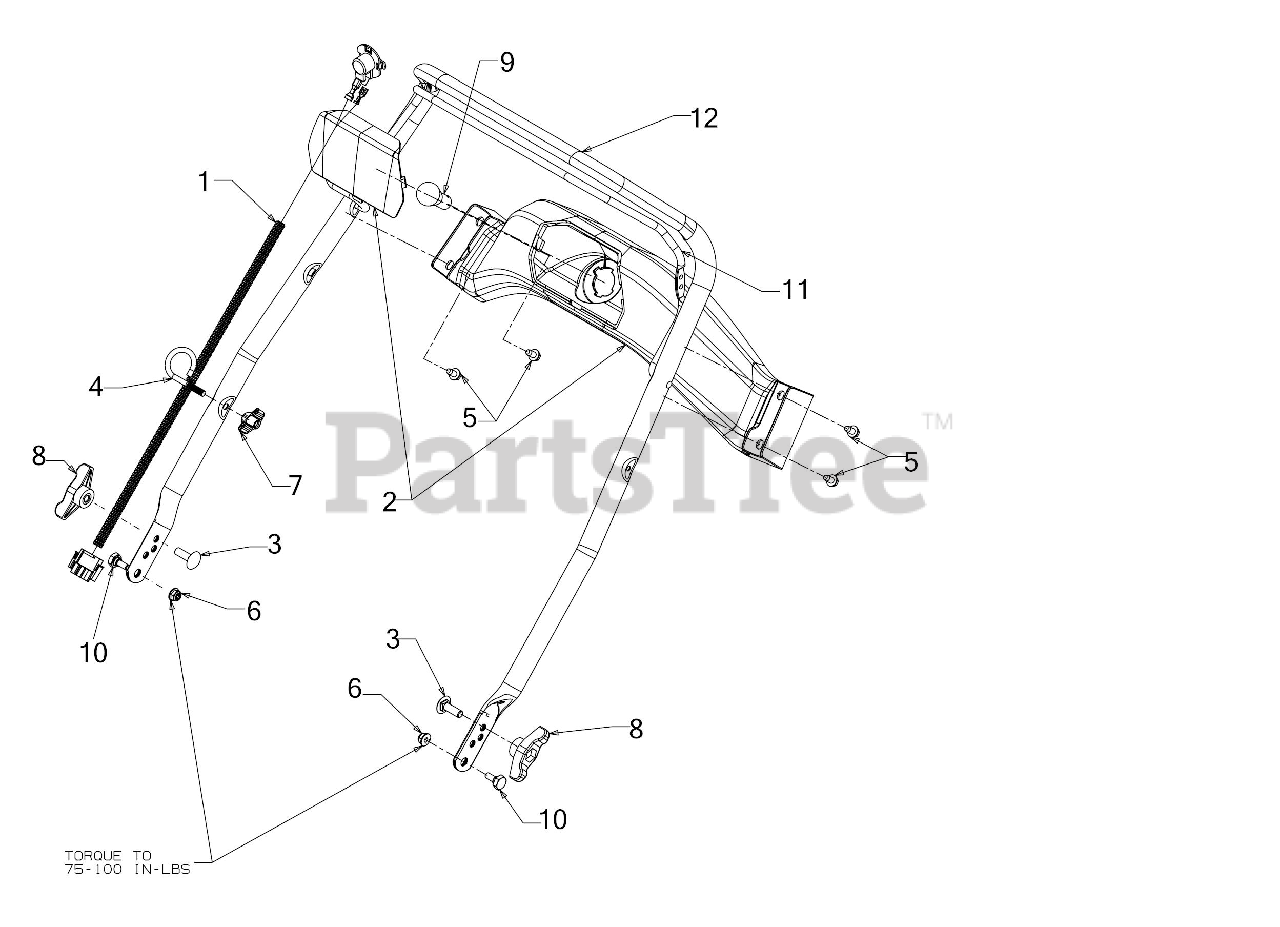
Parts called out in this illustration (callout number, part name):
1	LIGHT HARNESS ASSEMBLY
2	HANDLE PANEL ASSEMBLY
3	SCREW 5/16-18 x 1.00 GR5
4	EYEBOLT 1/4-20
5	SCREW 1/4-20 X.500
6	FLANGE LOCK NUT
7	HANDLE KNOB
8	WING KNOB 5/16-18
9	LAMP-#1683
10	SHOULDER SCREW
